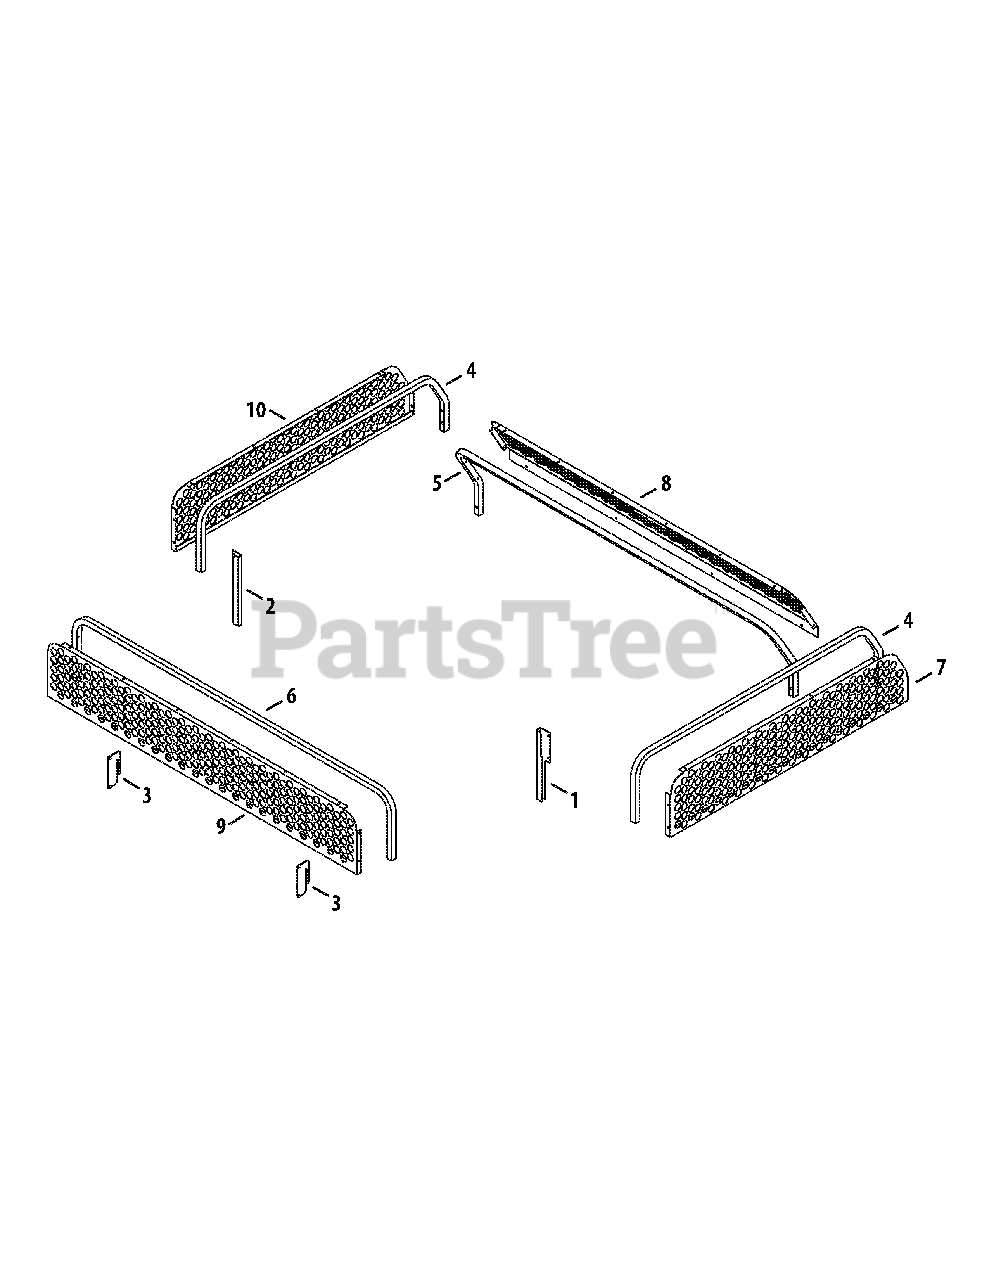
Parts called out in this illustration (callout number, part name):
1	Brace, Side Extension RH
2	Brace, Side Extension LH
3	Brace, Tailgate
4	Frame, Upper Side
5	Frame, Upper Front
6	Frame, Tailgate
7	Panel, Side RH
8	Panel, Front
9	Panel, Tailgate
10	Panel, Side LH
